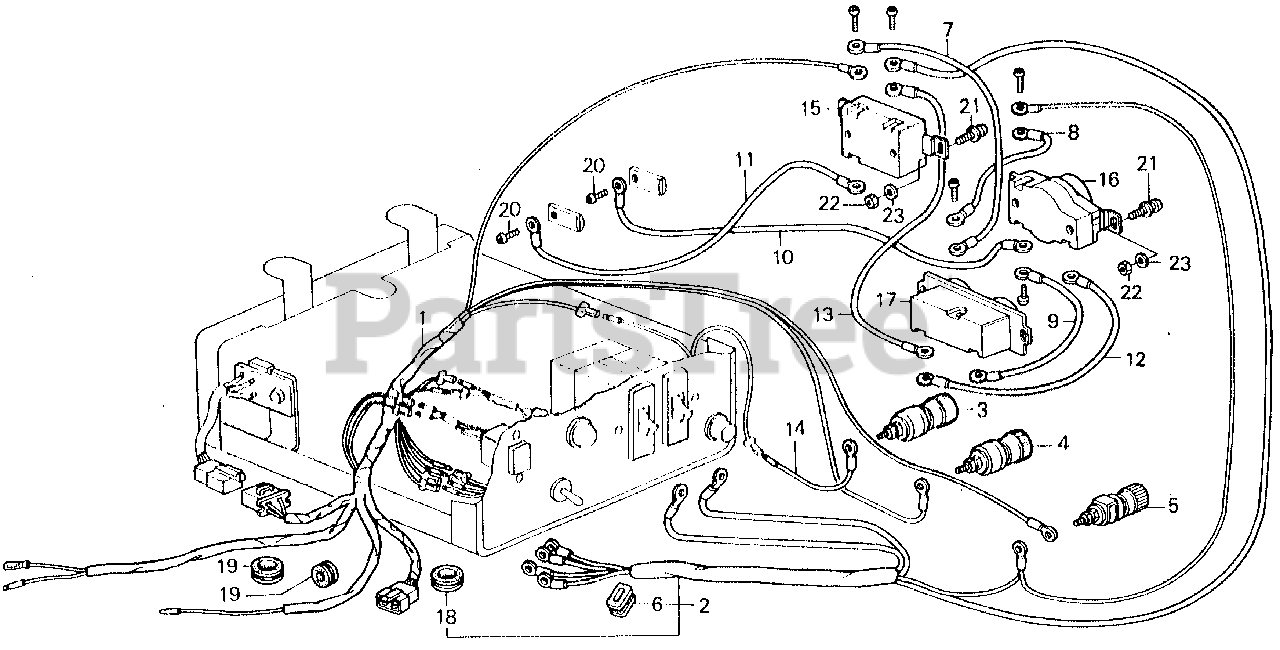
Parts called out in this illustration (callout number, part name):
1	WIRE HARNESS
2	WIRE, A.C. OUTLET
3	TERMINAL, D.C. OUT (+)
4	TERMINAL, D.C. OUT (-)
5	TERMINAL ASSY., GROUND (NOT AVAILABLE)
6	GROMMET, A.C. WIRE
7	WIRE, RECEPTACLE CONNECTING (200)
8	WIRE, RECEPTACLE CONNECTING (100)
9	WIRE, RECEPTACLE CONNECTING (100) (NOT AVAILABLE)
10	WIRE, RECEPTACLE CIRCUIT BREAKER CONNECTING (100)
11	WIRE, RECEPTACLE CIRCUIT BREAKER CONNECTING (200)
12	WIRE, RECEPTACLE CONNECTING (100) (GROUND) (NOT AVAILABLE)
13	WIRE, RECEPTACLE CONNECTING (200) (GROUND)
14	WIRE, D.C. OUT
15	RECEPTACLE (20A-250V)
16	RECEPTACLE (30A 250V)
17	RECEPTACLE (15A-125V)
18	GROMMET B, TUBE
19	GROMMET, WIRE HARNESS
20	SCREW, PAN (5X8)
21	SCREW-WASHER (4X12)
22	NUT, HEX. (4MM)
23	WASHER, PLAIN (4MM)
